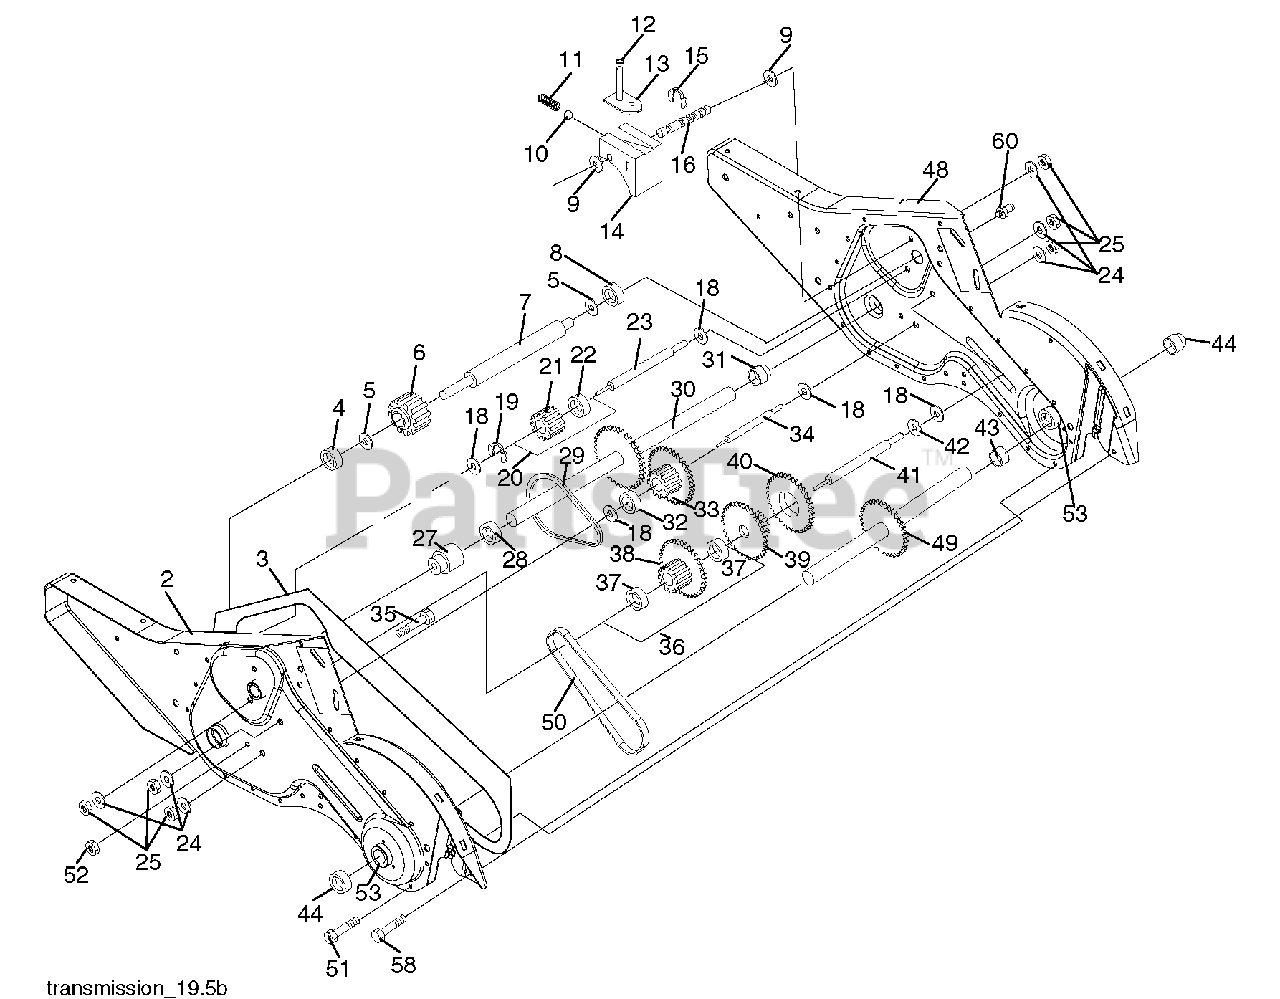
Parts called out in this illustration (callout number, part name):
1	Transmission Assembly
2	Gearcase, L.H. w/Bearing
3	Gasket, Gearcase
4	Bearing, Needle
5	Washer, Thrust 5/8 x 1.10 x 1/32
6	Pinion, Input
7	Shaft, In put
8	Bearing, Needle
9	Washer, Seal
10	Ball, Steel
11	Spring, Shift, Fork
12	O-Ring
13	Asm. Bracket Shift
14	Fork, Shift
15	Ring, Klip
16	Shaft, Shift
18	Washer
19	Ring, Klip
20	Gear, As sem bly, Reverse Idler
21	Gear, Re verse Idler
22	Bearing, Needle
23	Shaft, Re verse Idler
24	Washer, Lock 7/16
25	Nut, Hex 7/16-20
27	Bearing, Shaft, Ground Drive L.H.
28	Spacer 0.765 x 1.125 x 1.23
29	Chain #35-50 Pitch
30	Ground Shaft Assembly
31	Bearing, Shaft, Ground Drive R.H.
32	Spacer 0.70 x 1.00 x 1.150
33	Sprocket and Gear Assembly
34	Shaft, Re duc tion (2nd)
35	Screw, Whiz, Lock 5/16-18 x 3-1/2
36	Sprocket Assembly w/Bearing
37	Bearing, Needle
38	Sprocket, Tine
39	Gear, Clus ter, Red 1st & 2nd
40	Gear, Re verse
41	Shaft, Re duc tion (1st)
42	Washer, Thrust
43	Spacer 1.01 x 1.75 x 0.760
44	Seal Asm, Oil
48	Gearcase, R.H. w/Bearing
49	Shaft, Tine
50	Chain, Roller #50-50 Pitch
51	Screw 1/4-20 x 1/2
52	Nut, Hex 5/16-18
53	Kit, Bearing
58	Bolt Shoulder
60	Fitting Grease
60	Grease, Plastilube #1
